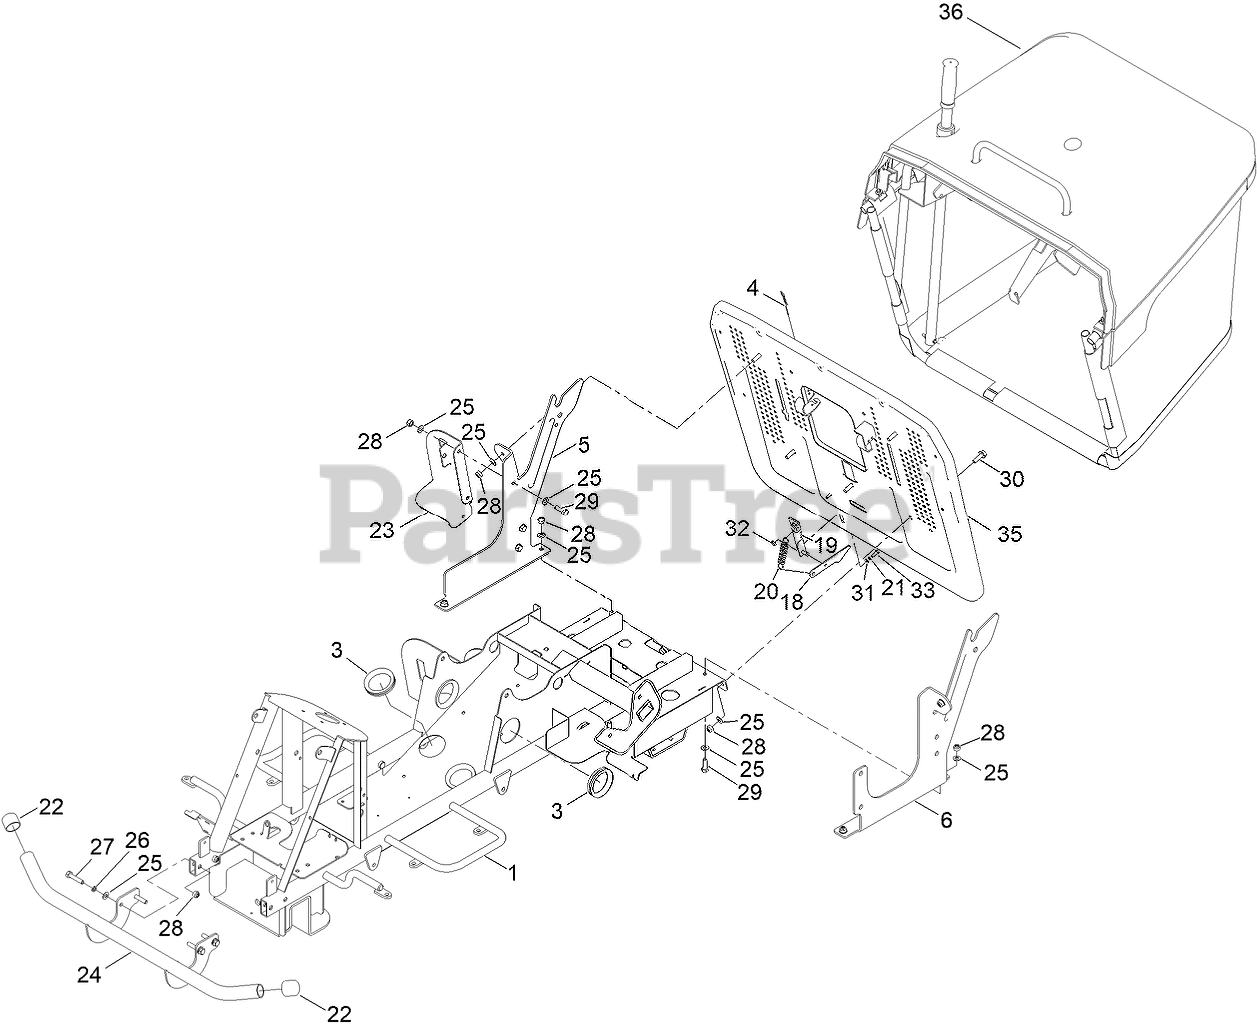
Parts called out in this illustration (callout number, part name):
1	CHASSIS, DIRECT COLLECT
3	RUBBER RING
4	PIN, CHUTE
5	MOUNT, GRASSBAG
6	MOUNT, GRASSBAG
18	PLATE, LATCH (GRASSBAG)
19	BRACKET, LATCH (GRASSBAG)
20	SPRING, LATCH (GRASSBAG)
21	SPRING WASHER
22	CAP, BUMPER
23	BRACKET, BATTERY
24	BUMP BAR
25	WASHER-PLAIN
26	WASHER-SPRING
27	BOLT
28	NUT-HEX, NI
29	SCREW-HH
30	SCREW-HHF
31	WASHER
33	SCREW-HH
35	MOUNTING PLATE, GRASSBAG
36	GRASS BAG ASM
